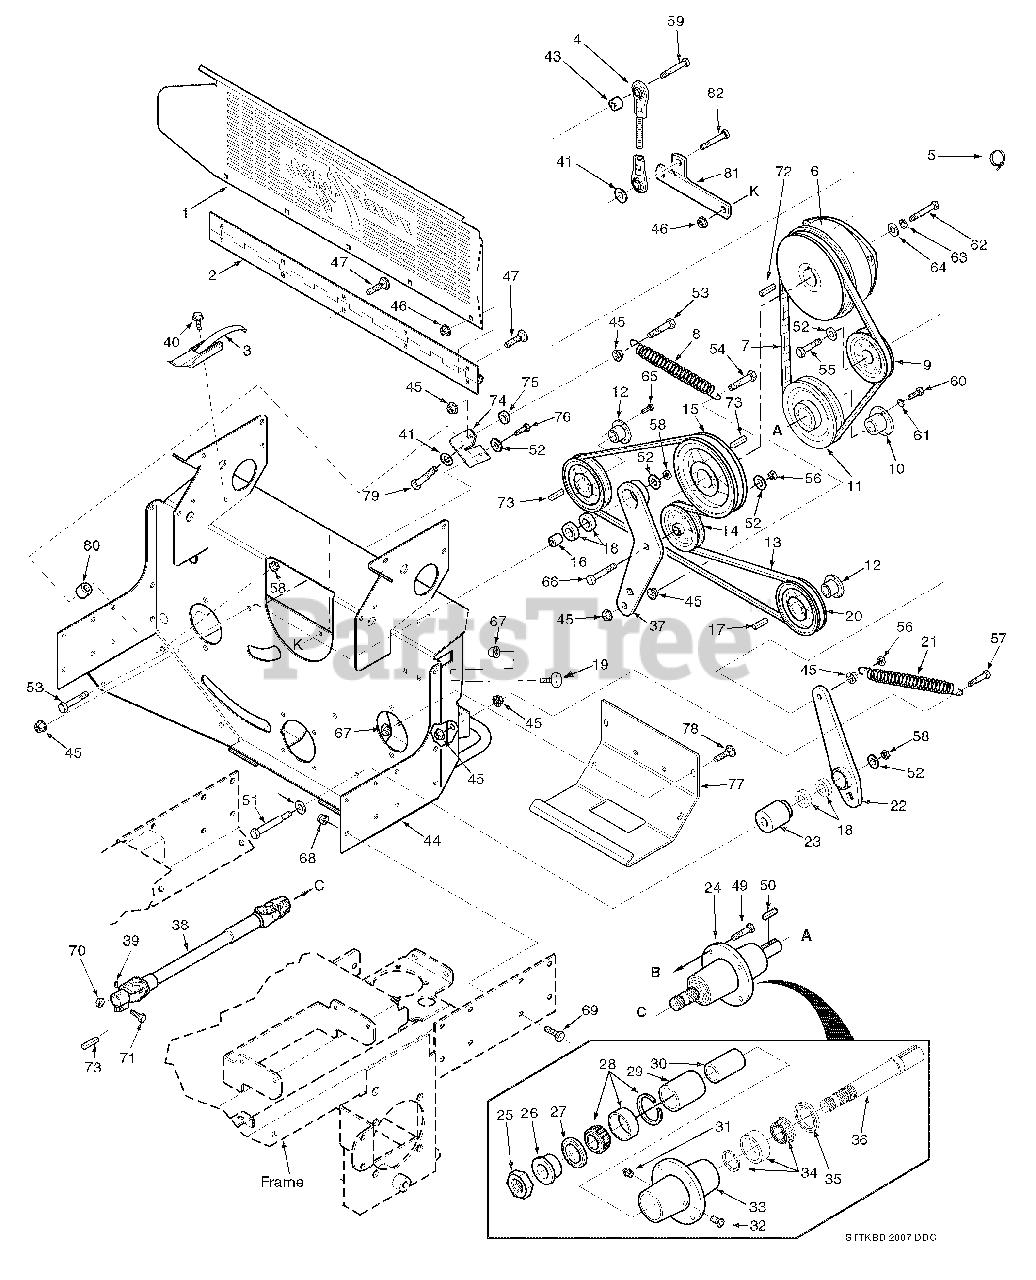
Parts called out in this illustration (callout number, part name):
1	Belt Guard, Rear
2	Hinge, Belt Guard
3	Latch, Hood
4	Rod Assembly, Clutch Anti-Rotation
5	Clamp, Cable
6	Clutch, Ogura GT-3.5
7	Belt, Deck Drive
8	Spring, Transmission Idler
9	Pulley, Idler 5” Dia.
10	Tapered Hub, 1” Bore
11	Pulley, 6.35 Tapered Bore
12	Tapered Hub, 17mm Bore
13	Belt, Pump Drive
14	Pulley, Idler 4” Dia.
15	Pulley, 5.35 Dia.-1.125 Bore
16	Spacer, Idler Bearing
17	Key, 5.0 x 5.0 x 25mm
18	Ball Bearing
19	Bumper, Rubber
20	Pulley,6.35” OD Tapered Bore
21	Spring, PTO
22	Idler Arm Weldment, PTO Drive
23	Pivot, Idler PTO
24	Spindle Assembly, Deck Drive
25	Nut, 1.06-18 Thread
26	Spindle Bushing, Bottom
27	Seal, 2.0 OD x 1.625 Bore
28	Roller Bearing Tapered
29	Spacer, Outside
30	Spacer, Inside
31	Grease Fitting, 1/4-28
32	Relief Fitting
33	Spindle Housing
34	Roller Bearing Tapered
35	Seal, 2.0 OD x 1.5 Bore
36	Shaft, Deck Drive
37	Idler Arm Weldment, Pump Drive
38	Driveshaft
39	Set Screw, 3/8-16 x 3/4” Torx Socket
40	Screw, #10-32 x .56
41	Flatwasher, 3/8-.391 x .938 x .105
42	Pin, Rue Cotter 3/8 Dia.
43	Spacer
44	Pump Mounting Plate Weldment
45	Nut, Serrated Flange 3/8-16
46	Nut, Serrated Flange 1/4-20
47	Bolt, Carriage 1/4-20 x 1/2”
48	Nut, Elastic Stop 5/16-18 Grade 8
49	Bolt, Hex Head 5/16-18 x 1-3/4” Grade 8
50	Key, 1/4 x 1/4 x 1-1/2”
51	Bolt, Hex Head 3/8-16 x 4-1/2” Grade 8 Black
52	Washer, 3/8 Hardened
53	Bolt, Hex Head 3/8-16 x 1-3/4” Grade 8 Black
54	Bolt, Hex Head 3/8-16 x 1-1/2” Grade 8 Black
55	Bolt, Hex Head 3/8-16 x 2-1/2” 1.5 Thread Grd.8
56	Nut, Center Lock 3/8-16
57	Bolt, Hex Head 3/8-16 x 1-1/2” Grade 8 Black
58	Nut, Elastic Stop 3/8-16
59	Bolt, Hex Head 3/8-16 x 2”
60	Bolt, Hex Head 1/4-20 x 1-3/8”
61	Lockwasher, 1/4 Spring
62	Bolt, Hex Head 7/16-20 x 2-1/2” UNF
63	Lockwasher, 7/16 Spring
64	Flatwasher, 7/16-.469 x 1.75 x .25
65	Bolt, Hex Head 1/4-20 x 1” Grade 8
66	Bolt, Hex Head 3/8-16 x 1-3/4”
67	Nut, Serrated Flange 5/16-18
68	Nut, Elastic Stop 3/8-16
69	Bolt, Hex Head 3/8-16 x 1”
70	Nut, Center Lock 3/8-16
71	Bolt, Hex Head 3/8-16 x 1-3/4”
72	Key, 1/4 x 1/4 x 2-1/4”
73	Key, 1/4 x 1/4 x 1”
74	Bracket
75	Spacer
76	Bolt, Hex Head 3/8-16 x 1”
77	Cover, Rear
78	Bolt, Carriage 5/16-18 x 3/4”
79	Bolt, Hex Head 3/8-16 x 2”
80	Spacer
81	Anchor Bracket, Anti-Rotation
82	Bolt, Hex Head 5/16-18 x 1-1/4”
